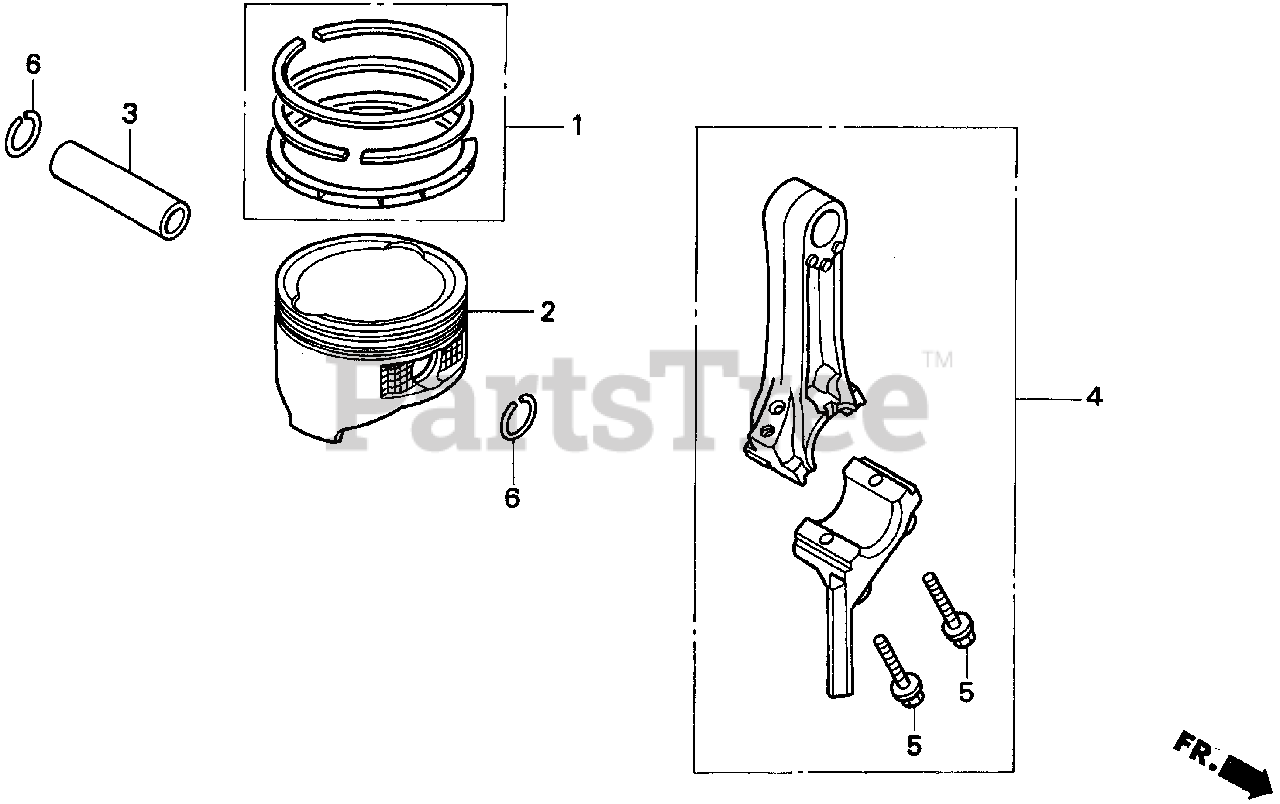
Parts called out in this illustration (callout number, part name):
1	RING SET, PISTON (RIKEN)
1	RING SET, PISTON (TEIKOKU)
2	PISTON
3	PIN, PISTON
4	ROD ASSY., CONNECTING
5	BOLT, CONNECTING ROD
6	CLIP, PISTON PIN (13MM)
